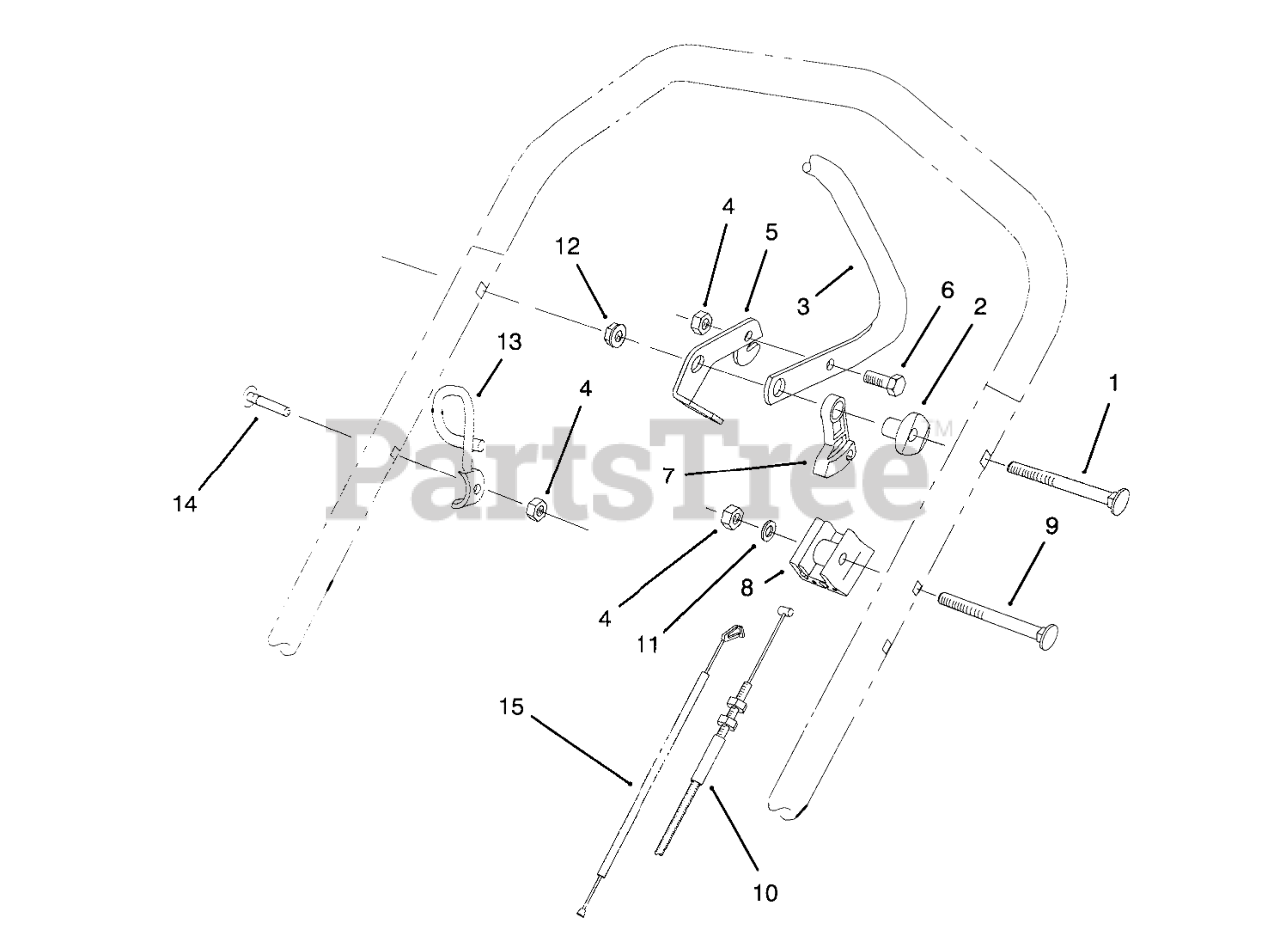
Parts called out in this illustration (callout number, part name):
1	SCREW-HANDLE
2	SPACER-SUPPORT
3	Bar-Control
4	NUT-LOCK, NI
5	LEVER-CONTROL
6	SCREW-HH
7	LEVER-TRACTION
8	SUPPORT-CABLE
9	SCREW-HANDLE
10	TRACTION CABLE
11	WASHER-FLAT
12	NUT-LOCK, NI
13	GUIDE-ROPE
14	Screw-Handle
15	CABLE - BRAKE
